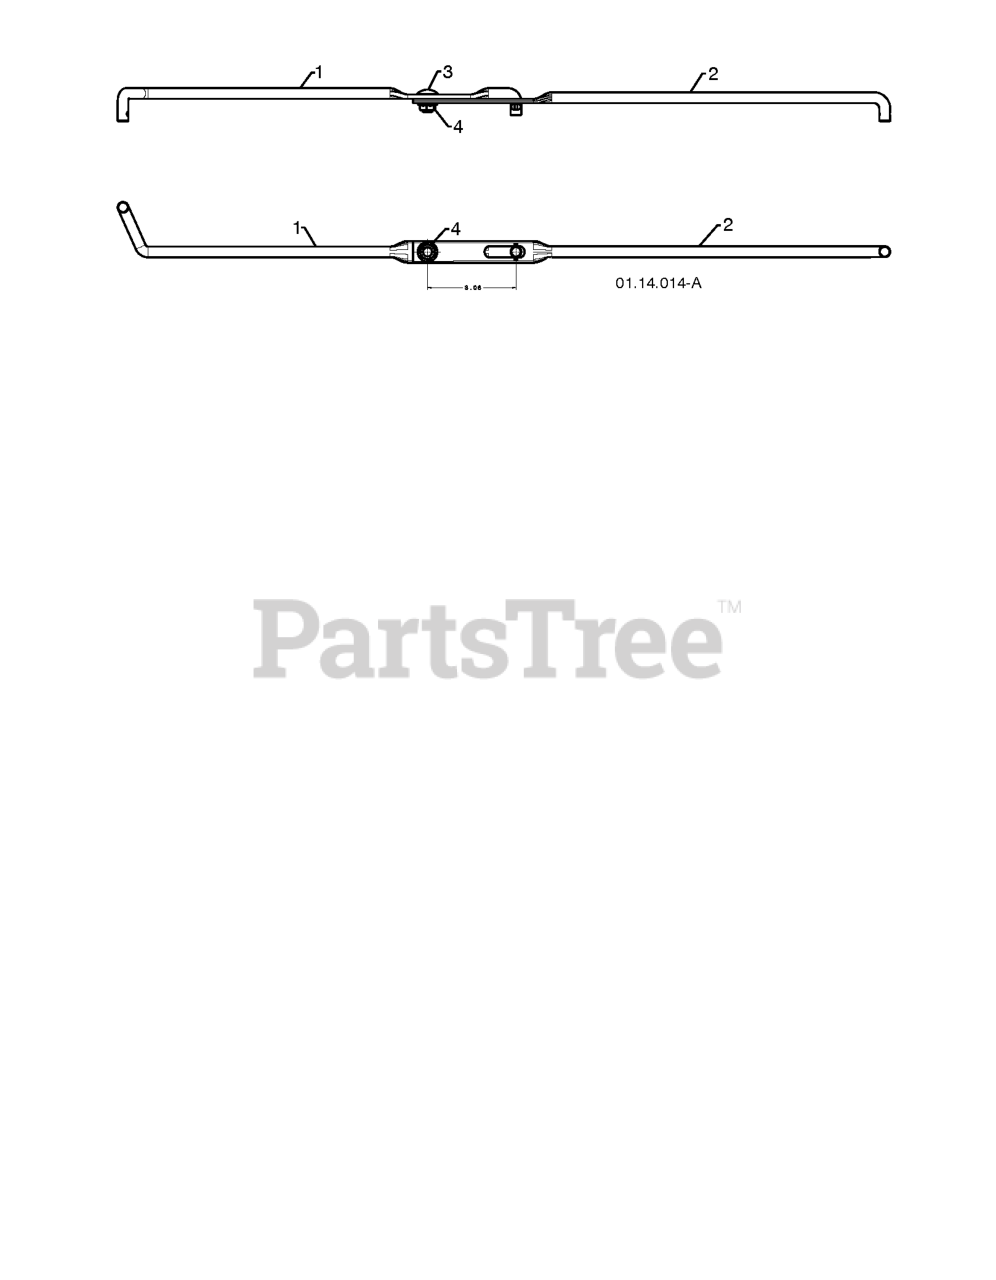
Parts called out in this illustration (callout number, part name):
1	ROD.SHIFTER.TOP.HYD.SNOW
2	ROD, LOWER, SPEED CONTROL
3	BOLT
4	NUT.FLANGE.5/16
